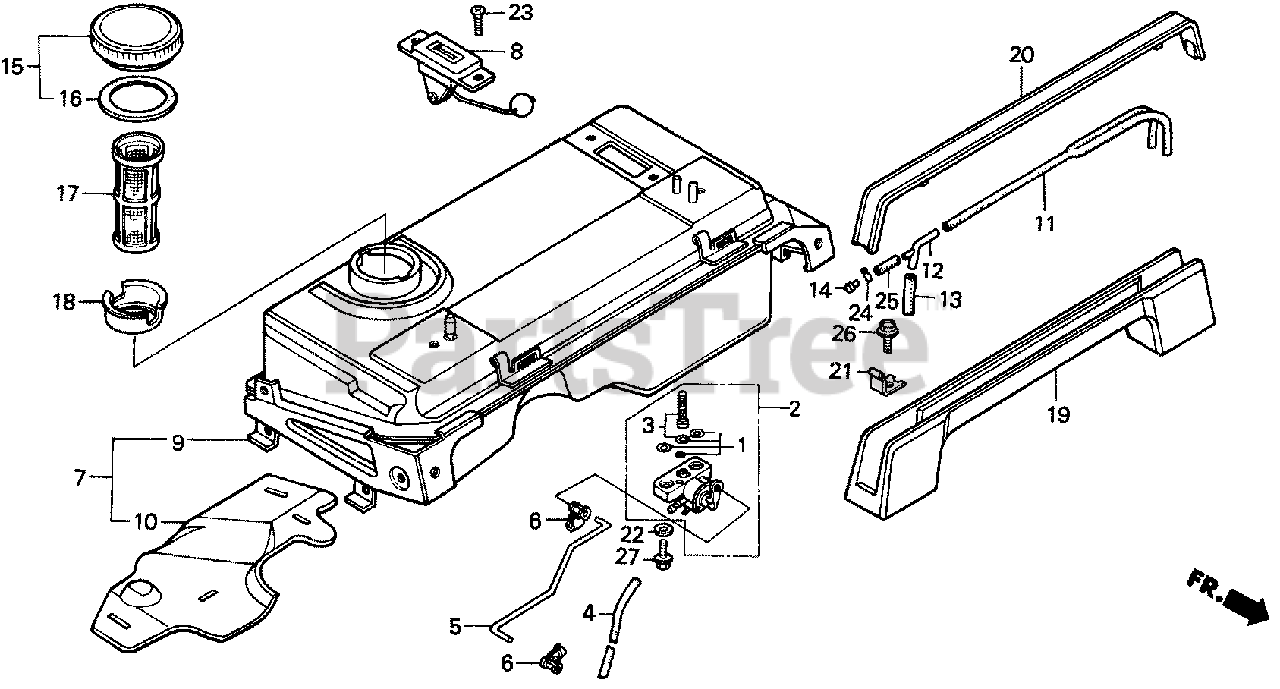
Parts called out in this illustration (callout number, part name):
1	GASKET SET, PETCOCK
2	PETCOCK ASSY.
3	SCREEN, FUEL STRAINER
4	TUBE, PETCOCK BREATHER
5	ROD, PETCOCK
6	JOINT, ROD
7	TANK ASSY., FUEL *NH151M* (JAZZY GRAY METALLIC)
7	TANK ASSY., FUEL *R280* (POWER RED)
8	METER ASSY., FUEL
9	TANK ASSY., FUEL *NH151M* (JAZZY GRAY METALLIC)
9	TANK ASSY., FUEL *R280* (POWER RED)
10	INSULATOR, HEAT
11	TUBE, HANDLE BREATHER
12	JOINT, BREATHER
13	TUBE B, HANDLE
14	FILTER, GASOLINE
15	CAP, FUEL FILLER
16	GASKET, FUEL FILLER CAP
17	FILTER, FUEL
18	HOLDER, FUEL FILTER
19	HANDLE, CARRYING
20	COVER, HANDLE
21	HOOK, HANDLE COVER
22	GASKET, FIBER (6MM)
23	SCREW, FLAT (5X10)
24	CLIP, TUBE (B7)
25	BULK HOSE, VACUUM (3.5X1000) (3.5X19)
26	BOLT, FLANGE (6X10)
27	BOLT, FLANGE (6X20)
